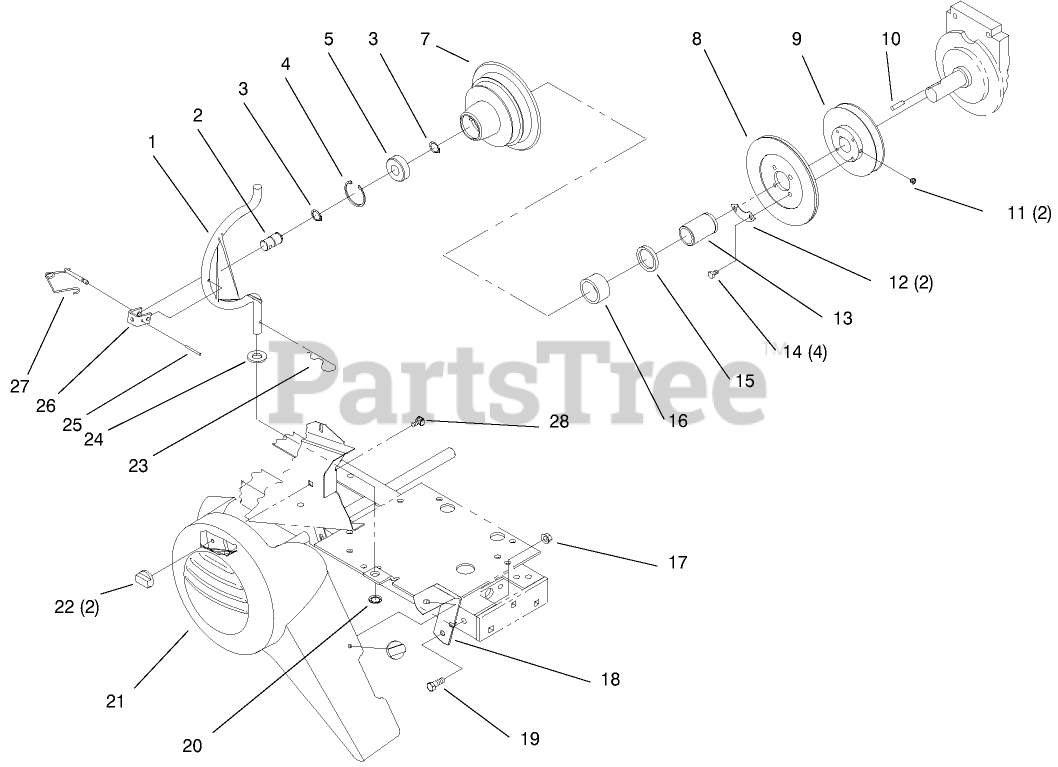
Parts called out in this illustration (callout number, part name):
1	ROD-HOUSING
2	SHAFT-PTO
3	RING-SNAP
4	RING-RETAINING
5	BEARING-BALL
8	ASS'Y-CLUTCH PLATE
11	SCREW-SET, HSH
12	RETAINER
13	RACE-BEARING
15	SEAL-OIL
17	NUT-FLANGE
19	SCREW-HH
20	RING-REINFORCED CIRC
21	GUARD - BELT
22	NUT - WING
23	PIN-COTTER, HAIR
24	WASHER-FLAT
25	PIN-ROLL
26	CLEVIS
27	LOCKING PIN ASM
